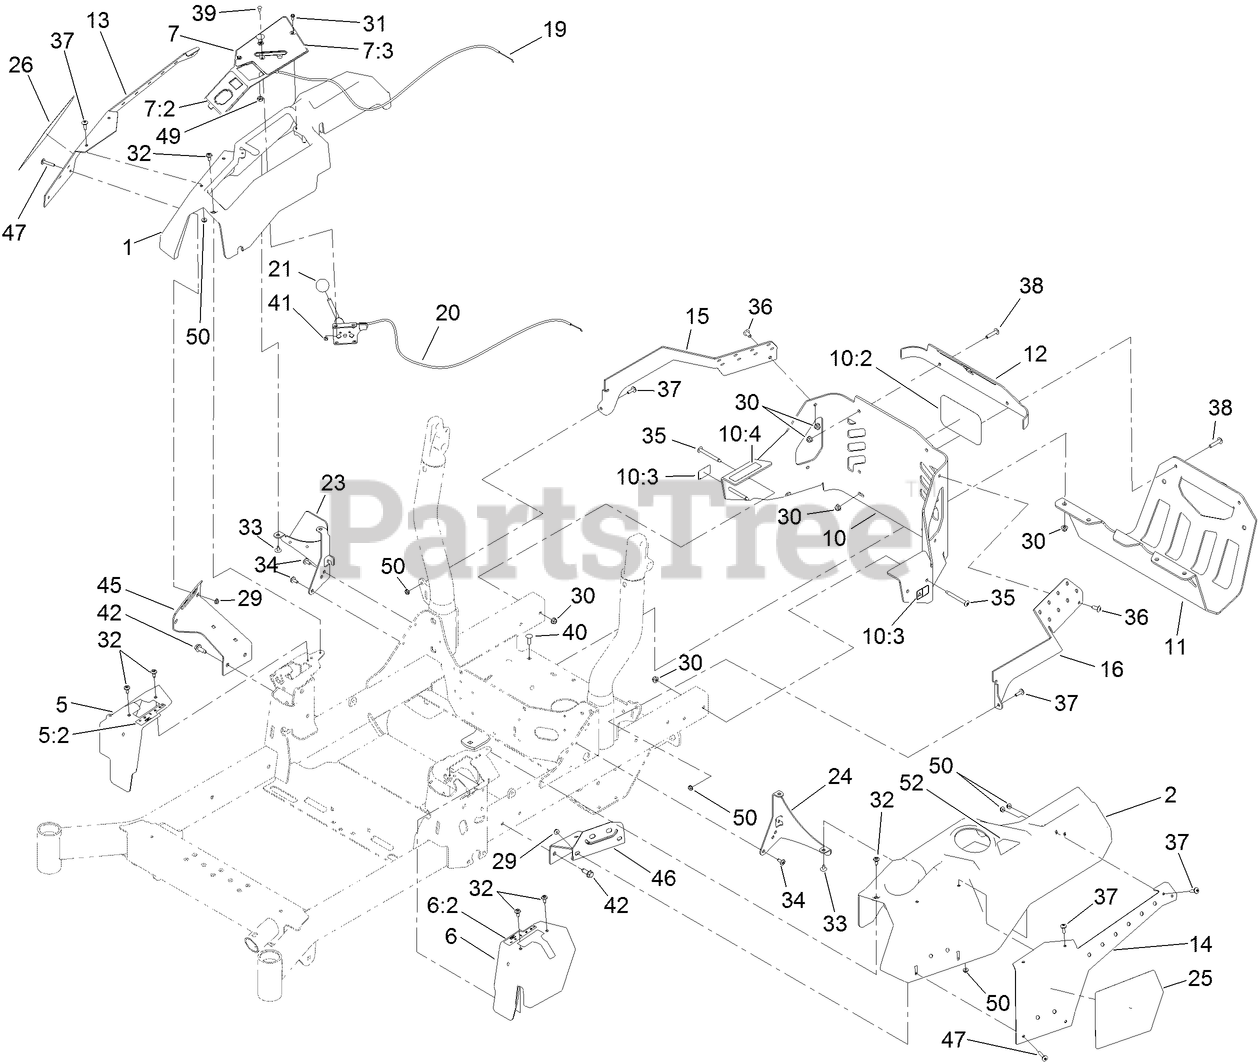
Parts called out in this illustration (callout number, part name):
1	CONSOLE-RH
2	CONSOLE-LH
5	COVER-CONTROL, MOTION (RH)
5:2	DECAL-CONTROL, MOTION (RH)
6	COVER-CONTROL, MOTION (LH)
6:2	DECAL-CONTROL, MOTION (LH)
7	CONTROL PANEL ASM
7:2	DECAL-PANEL, CONTROL
7:3	DECAL-PANEL, CONTROL
10	REAR GUARD ASM
10:2	DECAL
10:3	DECAL-WARNING
10:4	DECAL-ARRESTOR, SPARK
11	GUARD-MUFFLER
12	TRIM-UPPER REAR
13	COVER,POD RH
14	COVER [BLACK]
15	BRACKET-GUARD, RH
16	BRACKET-GUARD, LH
19	CABLE-CONTROL, CHOKE
20	CABLE-CONTROL, THROTTLE
21	KNOB-BALL
23	SUPPORT-CONSOLE, RH
24	BRACKET-CONSOLE, LH
25	DECAL-2000, LH
26	DECAL-2000, RH
29	NUT-HF
30	NUT-HF, NI
31	SCREW-HWH
32	SCREW-SHOULDER
33	SCREW-TORX
34	SCREW-TORX
35	SCREW-TORX
36	SCREW-TORX
37	SCREW-TRUSS
38	SCREW-TORX
39	BOLT-CARR
40	SCREW-CARR
41	NUT-LOCK, NI
42	SCREW-FORMING, THREAD
45	BRACKET-SUPPORT, POD (RH)
46	BRACKET-SUPPORT, POD (LH)
47	SCREW-TRUSS
49	NUT-HJ
50	NUT-KEPS
52	DECAL-FILL, FUEL
